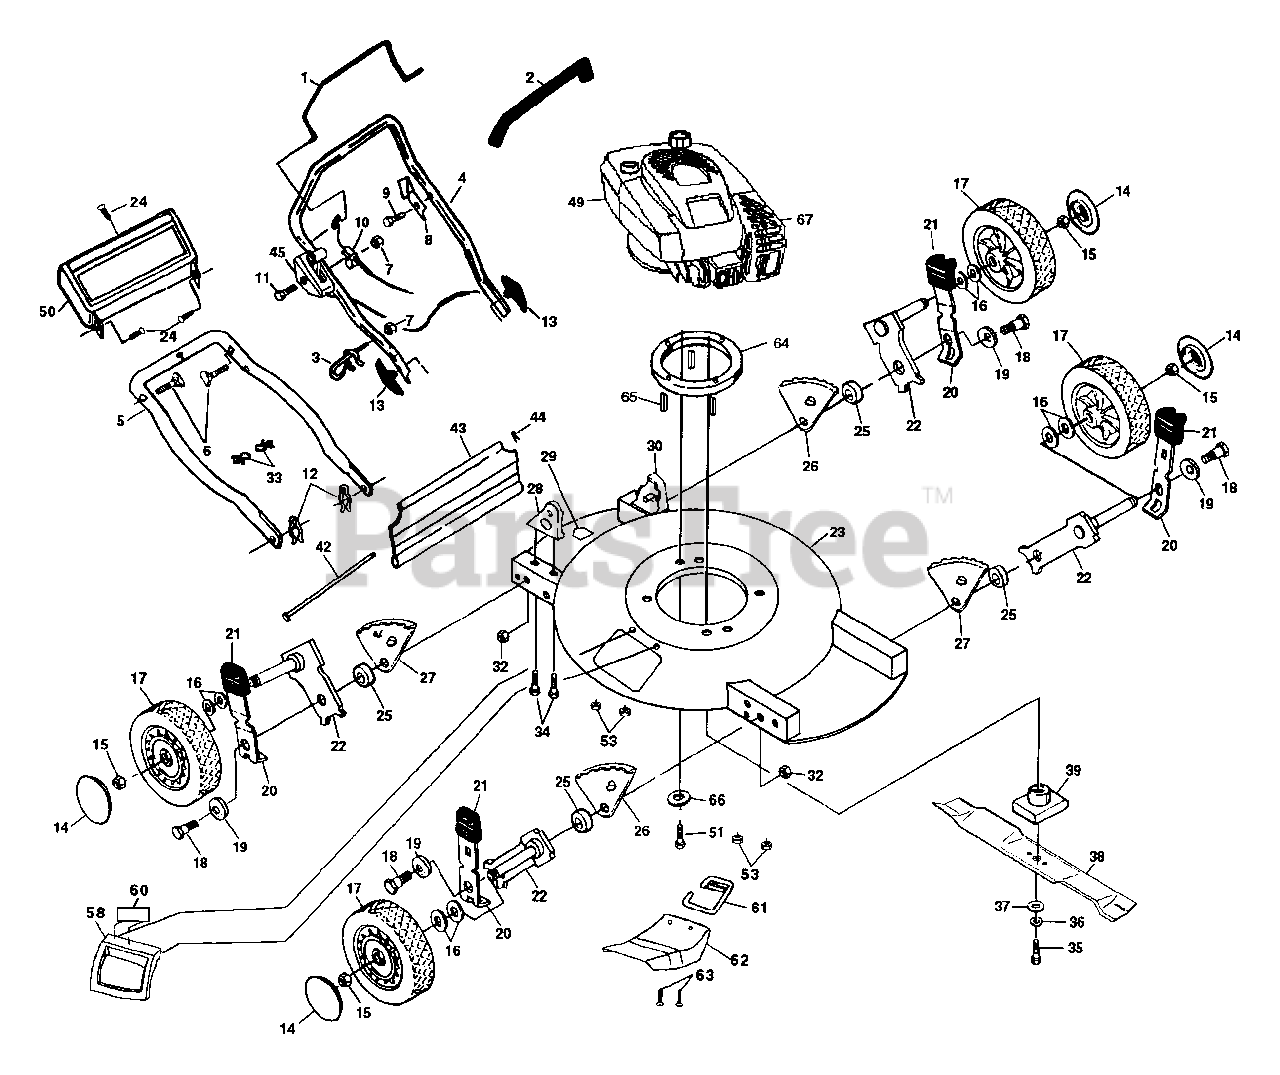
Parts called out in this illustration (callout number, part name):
1	Control Bar
2	Handle Grip
3	Rope Guide
4	Upper Handle
5	Lower Handle
6	Handle Bolt 5/16-18 x 1-3/4
7	Locknut 1/4-20
8	Up-Stop Bracket
9	Hex Washer Head Screw #10-24 x 1/2
10	Engine Zone Control Cable
11	Hex Washer Head Screw 1/4-20 x 2.12
12	Hairpin Cotter
13	Handle Knob
15	Hex Locknut 3/8-16
16	Washer
17	Wheel & Tire Assembly
18	Shoulder Bolt
19	Belleville Washer
20	Selector Spring
21	Selector Knob
22	Axle Arm Assembly
23	Lawn Mower Housing
24	Push-in Fastener
25	Spacer
26	Wheel Adjusting Bracket (R.F./L.R.)
27	Wheel Adjusting Bracket (L.F./R.R.)
28	Handle Bracket Assembly (Right)
29	Danger Decal
30	Handle Bracket Assembly (Left)
32	Locknut 3/8-16
33	Cable Clips
34	Thread Cutting Screw 5/16-18 x 3/4
35	Hex Head Screw 3/8-24 x 1-3/8
36	Helical Lockwasher 3/8
37	Hardened Washer
39	Blade Adapter
42	Deflector Rod
43	Rear Deflector
44	Retainer Clip
45	Throttle Control
49	Engine - Tecumseh
50	Trim Plate
51	Hex Head Screw, Self Tap. 3/8 - 16 x 1.1
53	Locknut
58	Mulcher Door
61	Chute Mounting Bracket
62	Mulcher Deflector
63	Truss Head Screw
64	Engine Spacer
65	Engine Bushing
67	Muffler Guard
